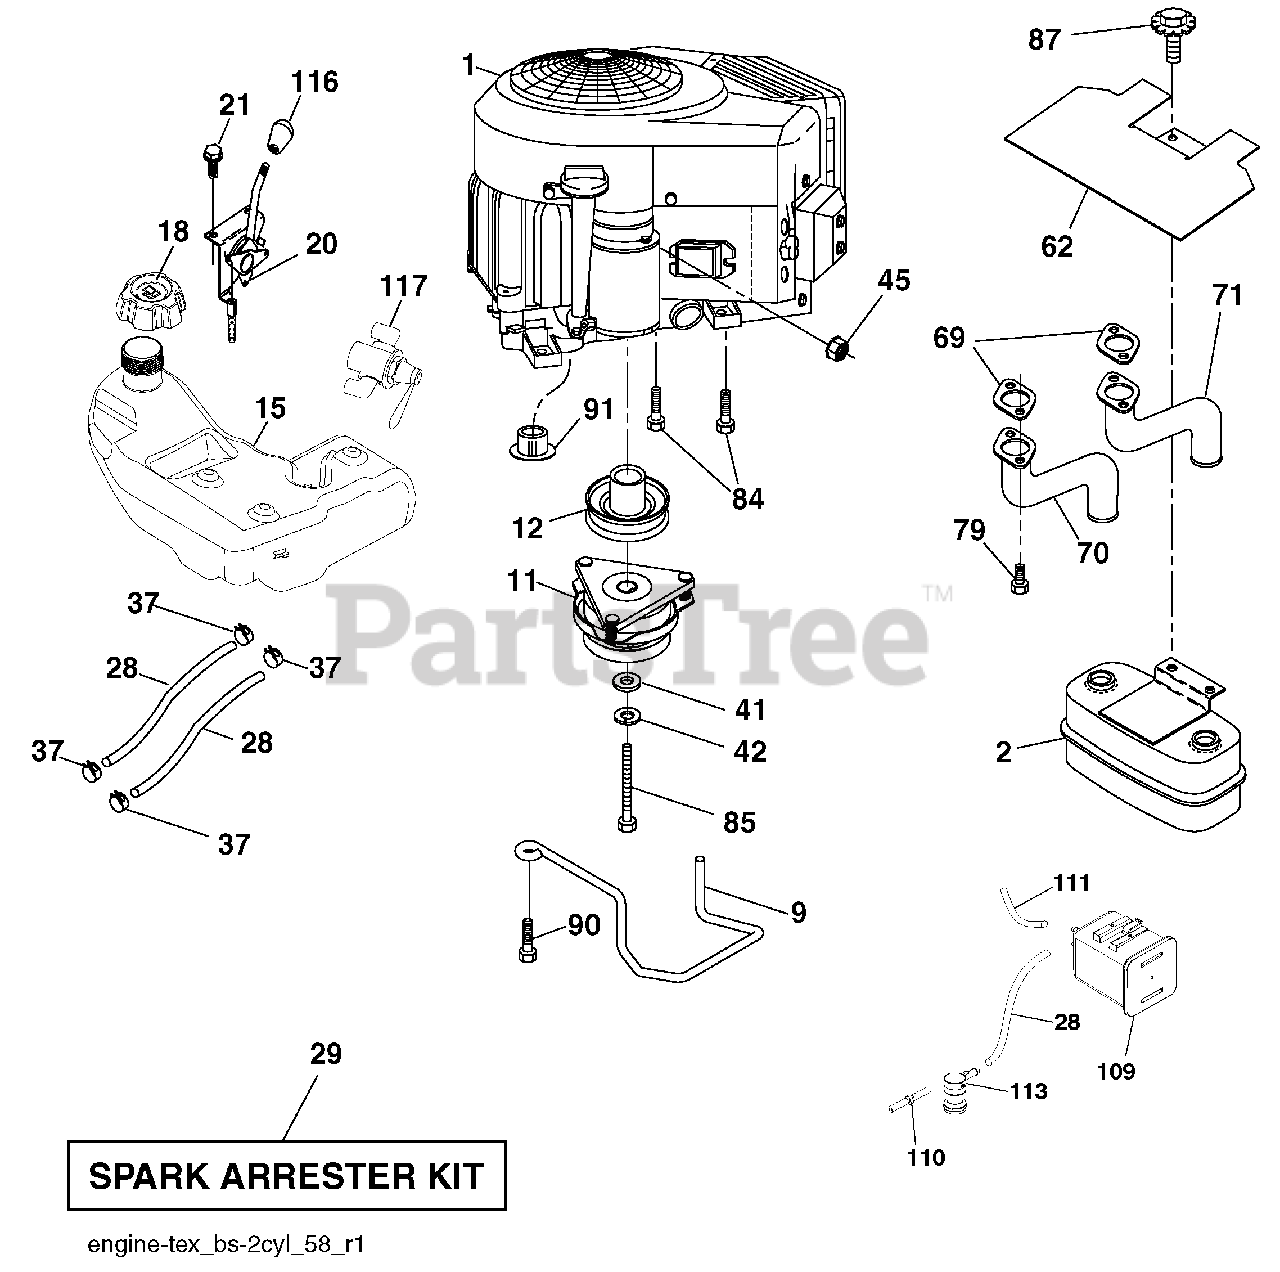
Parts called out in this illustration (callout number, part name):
9	Keeper Belt Engine
11	Clutch
12	Pulley Engine
15	Tank Fuel
18	Cap Asm
20	Control Throttle
21	Screw #10 x .750 BOS Thread
28	Fuel Line
29	Spark Arrester Kit
37	Clamp Hose
41	Washer 1-1/2 OD x 15/32 ID x .250
42	Washer Lock 7/16
45	Nut Keps Hex 1/4-20 unc
62	Heat Shield
70	Tube Exhaust LH
71	Exhaust Tube RH
79	Screw Socket HD 5/16-18 x 1
84	Screw 3/8-16 x 1-1/4
85	Bolt Hex 7/16-20 x 4 x Gr. 5-1.5 Thr
87	Bolt 5/16-18 UNC x 3/4 w/Sems
90	Screw 3/8-16 x 1
109	Canister Carbon Filter Asm
110	Valve Anti-Slosh
111	Purge Line
113	Valve Slant Cardrdg
116	Knob Soft Touch
117	Valve Fuel Reserve
